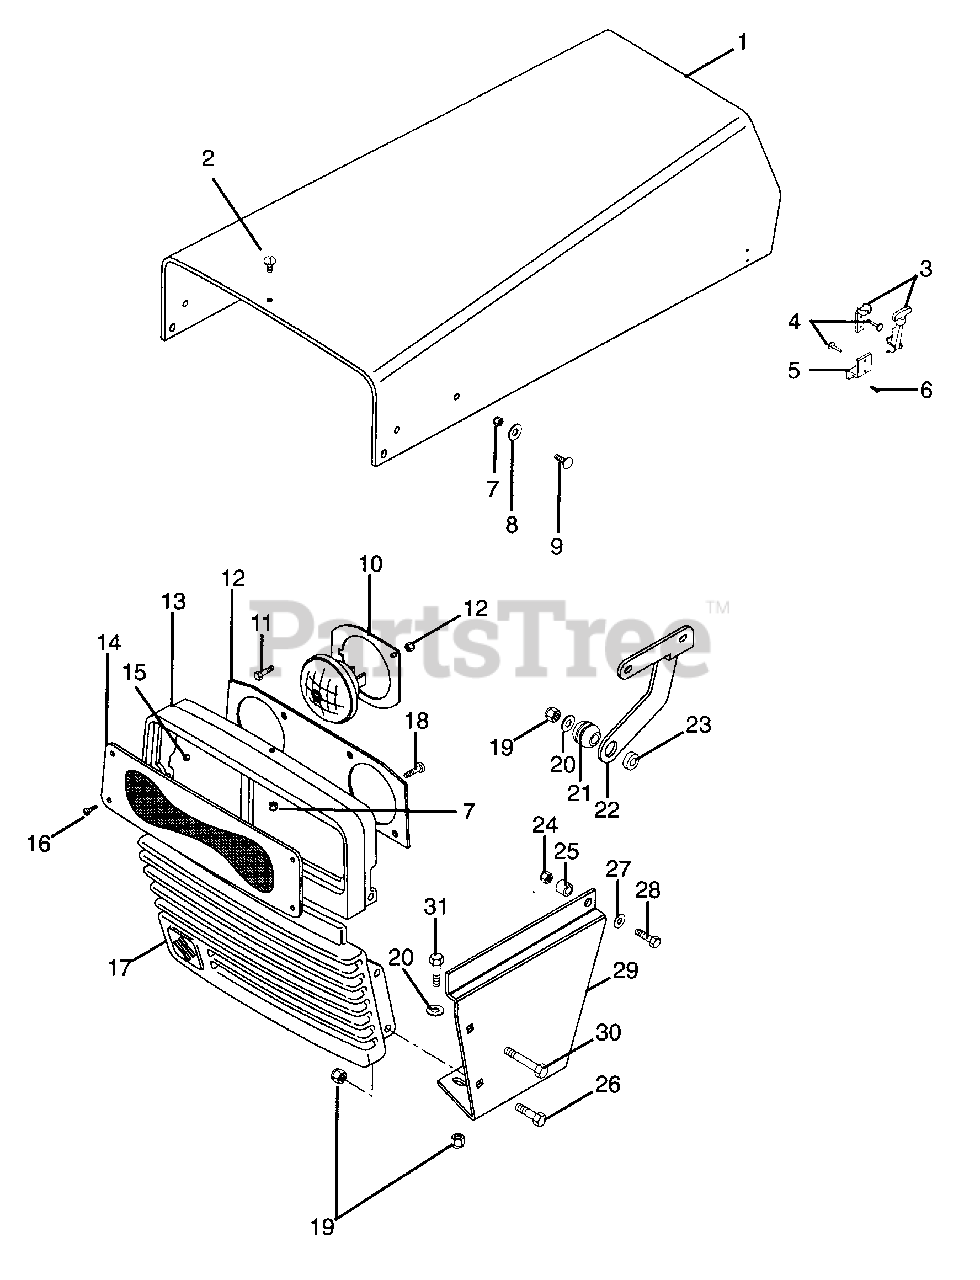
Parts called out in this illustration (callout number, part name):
1	Hood-Tractor
2	Screw-Machine .25-20 x .75
3	Latch-Flexible
4	Rivet .125 x .245
5	Bracket-Hood Latch Mounting
6	Screw-Tapping 8-32 x .50
7	Nut-Locking-Center .250-20 Grade 2
8	Washer-Flat .281 x .625 x .065
9	Bolt-Round Head Square Neck .25-20 x .75
10	Head Light Retainer Ring
11	Bolt-Hex .25-20 x 1.000 Grade 5
12	Panel-Headlight Reflector
13	Bezel-Headlight
14	Panel-Headlight Lens
15	Nut-Locking-Nylon 10-24
16	Screw-Machine 10-24 x .750
17	Grill
18	Screw-Tapping .25-20 x .50
19	Nut-Locking-Center .375-16 Grade 2
20	Washer-Flat-Steel .438 x 1.0 x .083
21	Grommet
22	Left Hand Hood Hinge
22	Right Hand Hood Hinge
23	Spacer
24	Nut-Locking-Center .312-18 Grade 2
25	Bushing-Sleeve .406 x 1.00 x 1.00
26	Bolt-Hex .38-16 x 1.00 Grade 5
27	Washer-Flat-Steel .344 x .688 x .065
28	Bolt-Hex .31-18 x 1.75 Grade 5
29	Panel-Side Left Hand
29	Panel-Side Right Hand
30	Bolt-Hex .38-16 x 2.00 Grade 5
